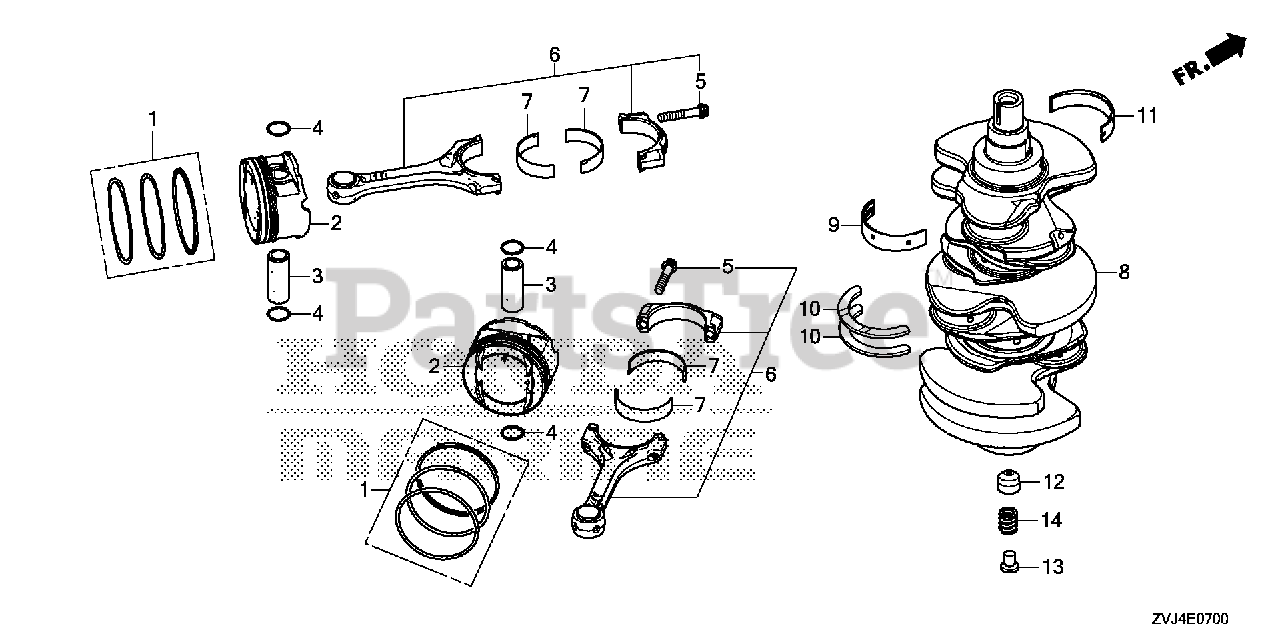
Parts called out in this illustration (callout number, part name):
1	RING SET, PISTON (STD) (RIKEN)
1	RING SET, PISTON (0.25) (RIKEN)
2	PISTON (0.25)
3	PIN, PISTON
4	CLIP, PISTON PIN
5	BOLT, CONNECTING ROD
6	ROD, CONNECTING
7	BEARING A, CONNECTING ROD (BLACK) (TAIHO)
7	BEARING B, CONNECTING ROD (BROWN) (TAIHO)
7	BEARING C, CONNECTING ROD (GREEN) (TAIHO)
7	BEARING D, CONNECTING ROD (YELLOW) (TAIHO)
7	BEARING E, CONNECTING ROD (PINK) (TAIHO)
8	CRANKSHAFT
9	BEARING A, MAIN (UPPER) (BLACK) (TAIHO)
9	BEARING B, MAIN (UPPER) (BROWN) (TAIHO)
9	BEARING C, MAIN (UPPER) (GREEN) (TAIHO)
9	BEARING D, MAIN (UPPER) (YELLOW) (TAIHO)
9	BEARING E, MAIN (UPPER) (PINK) (TAIHO)
9	BEARING F, MAIN (UPPER) (RED) (TAIHO)
10	WASHER, THRUST
11	BEARING A, MAIN (LOWER) (BLACK) (TAIHO)
11	BEARING B, MAIN (LOWER) (BROWN) (TAIHO)
11	BEARING C, MAIN (LOWER) (GREEN) (TAIHO)
11	BEARING D, MAIN (LOWER) (YELLOW) (TAIHO)
11	BEARING E, MAIN (LOWER) (PINK) (TAIHO)
11	BEARING F, MAIN (LOWER) (RED) (TAIHO)
12	RETAINER, SPRING
13	SEAT, SPRING (250)
14	SPRING, SUPPORT
